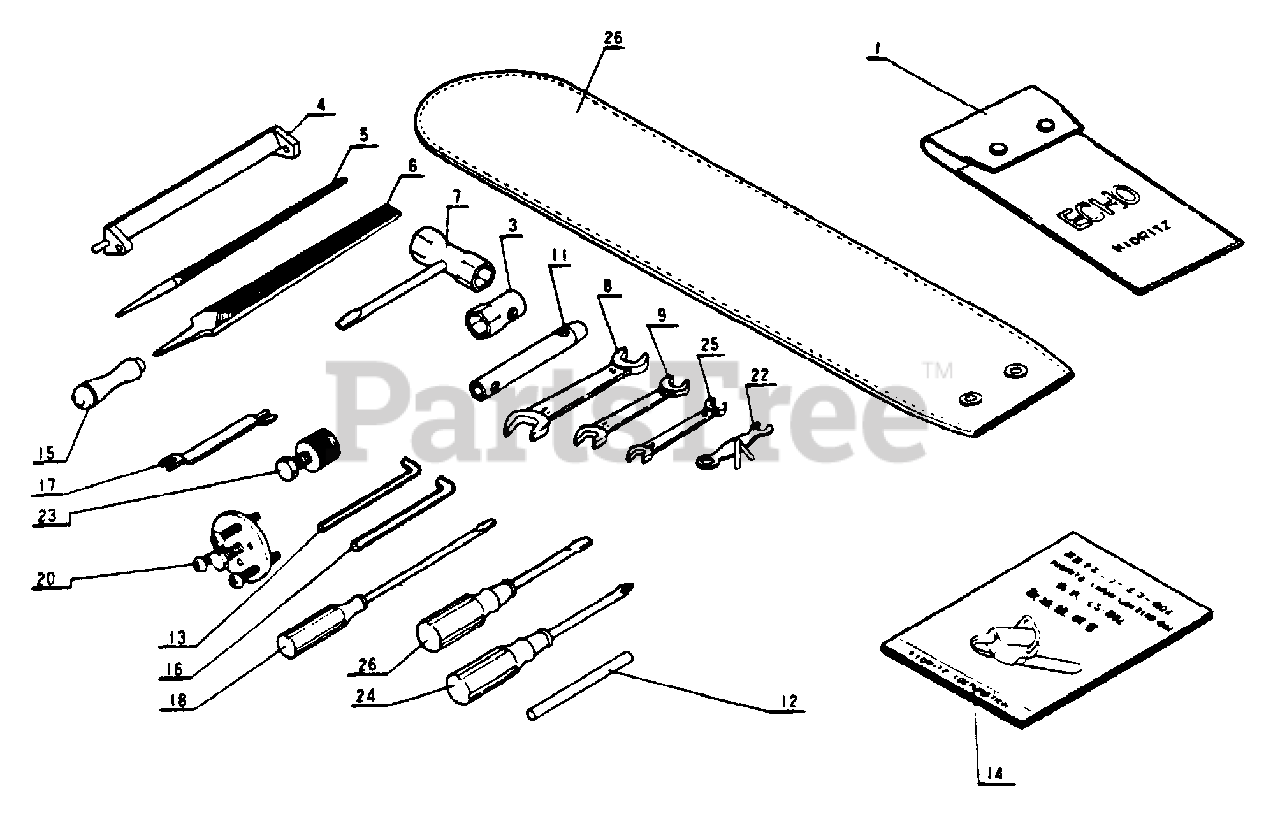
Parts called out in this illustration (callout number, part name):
1	BAG, TOOL
3	SOCKET WRENCH
4	File holder
5	FILE - ROUND
6	FILE - FLAT
7	T-WRENCH - 13X19mm
8	SPANNER
9	SPANNER
11	SOCKET WRENCH
12	SOCKET WRENCH
13	HEX KEY - 4mm
14	OWNER'S MANUAL
15	File grip
16	HEX KEY
17	DEPTH GAUGE
18	SCREWDRIVER
20	CLUTCH PULLER
22	Magneto spanner
23	MAGNETO PULLER
24	SCREWDRIVER - (+)
25	SPANNER
26	SCREWDRIVER - (-)
26	COVER, CHAIN
